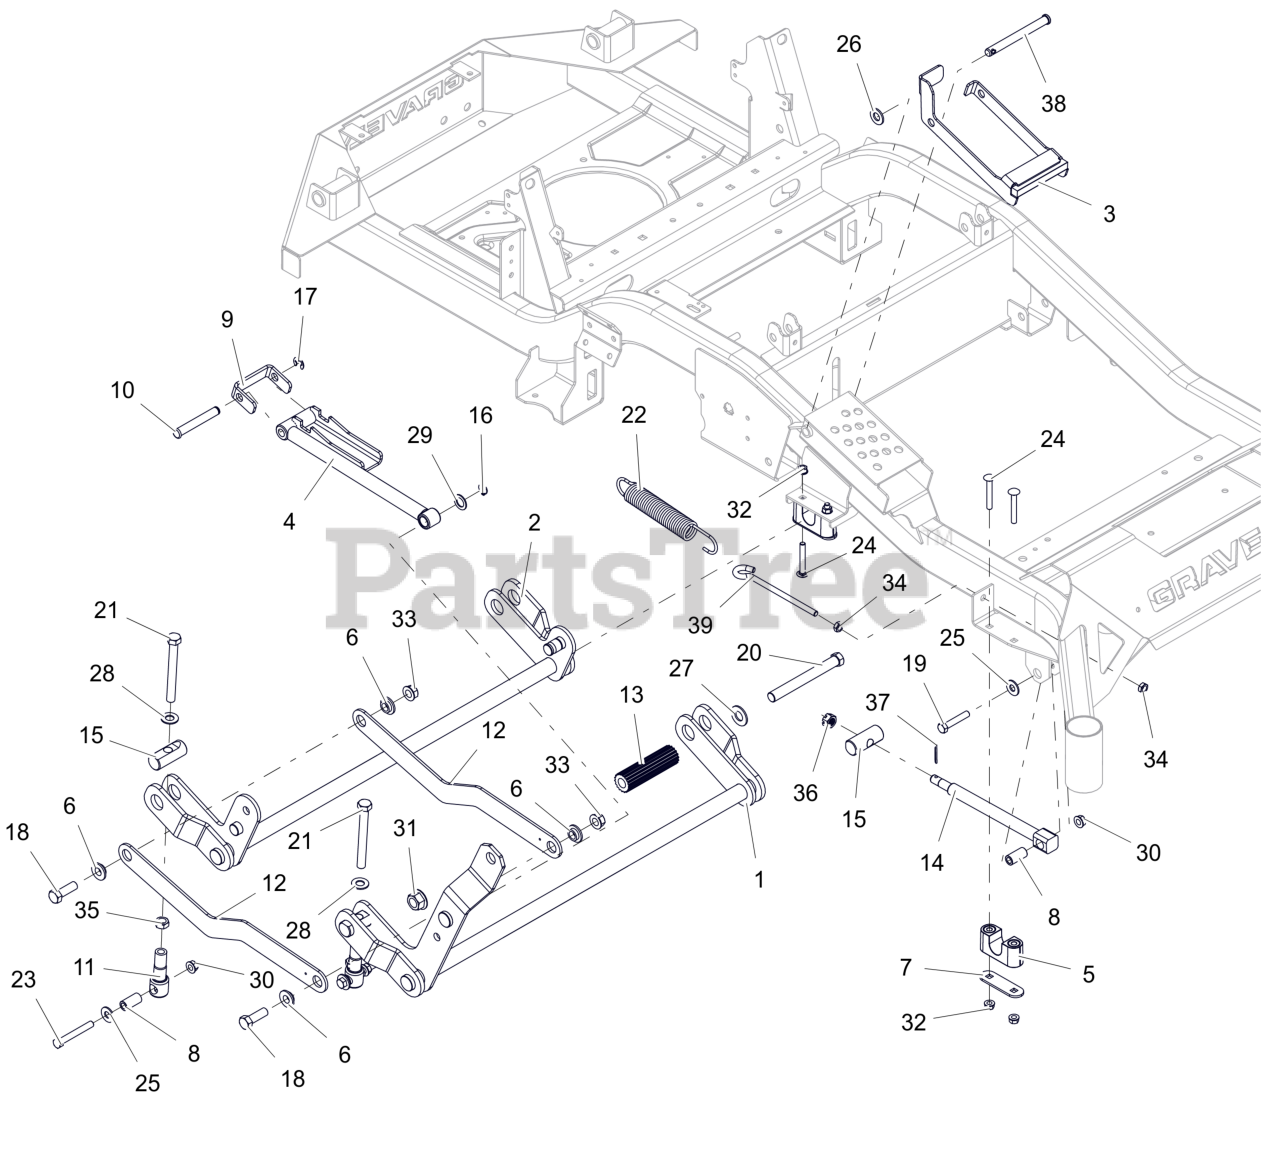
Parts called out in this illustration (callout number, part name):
1	WLDMT, FRONT DECK LIFT PIVOT
2	WLDMT, REAR DECK LIFT PIVOT
3	WLDMT, HOC TRANSFER LOCK (BLACK)
4	WLDMT, HOC LIFT ARM (BLACK)
5	ASM-BUSHING, DECK LIFT
6	BSHG-FLG .515X.750X.310X1.120
7	PLATE, BEARING SUPPORT
8	SPACER, DECK LEVELING
9	BRKT, HOC LINE
10	PIN, .499/.494 x 3.385 CLEVIS
11	LINK, DECK LIFT FORMED
12	LINK, DECK
13	ROD, FOOT PEDAL (BLACK)
14	DRAG,LINK-HD
15	PIN, DECK LIFT
16	RG-RTNG-EXT .625X.050
17	RG-RTNG-EXT .500X.042 (E)
18	BLT,HEX .50-13X1.50 G5 ZCC
19	BLT,HEX .38-16X2.00 G5 ZCC
20	BLT, HEX .62-11X5.50 G5 FBP
21	BLT, HEX .50-13X4.50F G8 ZCC
22	SG-TENS .162X1.25X8.25 WLD 25
23	BLT, HEX .38-16X2.75 G8 ZCC
24	BLT, RHSSN.31-18X2.25 G5 ZCC
25	WSHR,FLT .438X1.00X.083 ZCC
26	WSHR,FLT .531X1.062X.095 ZCC
27	WSHRFLT 5/8SAE CARBHARD FBP
28	WSHR, FLT .557X1.040X.102 ZCC
29	WSHR, FLT .630X1.005X.062 ZCC
30	NUT-LK-TOP-FLG .38-16 ZC120
31	NUT,FLG-TOP LK .625-11 FBP
32	NUT,LK-CTR-FLG .31-18 GF ZCC
33	NUT-LK-TOP-FLG .500-13 GF ZCC
34	NUT-JAM .375-16 G2 ZCC
35	NUT-JAM .500-13 G2 ZCC
36	NUT-SL .50-13
37	PIN,CTR.12X1.25EXTPRSQCT ZC120
38	PIN, SLIC-.500X4.97X4.55 -ZC
39	BOLT,.38-16 X 5.25-.62 DIA EYE
